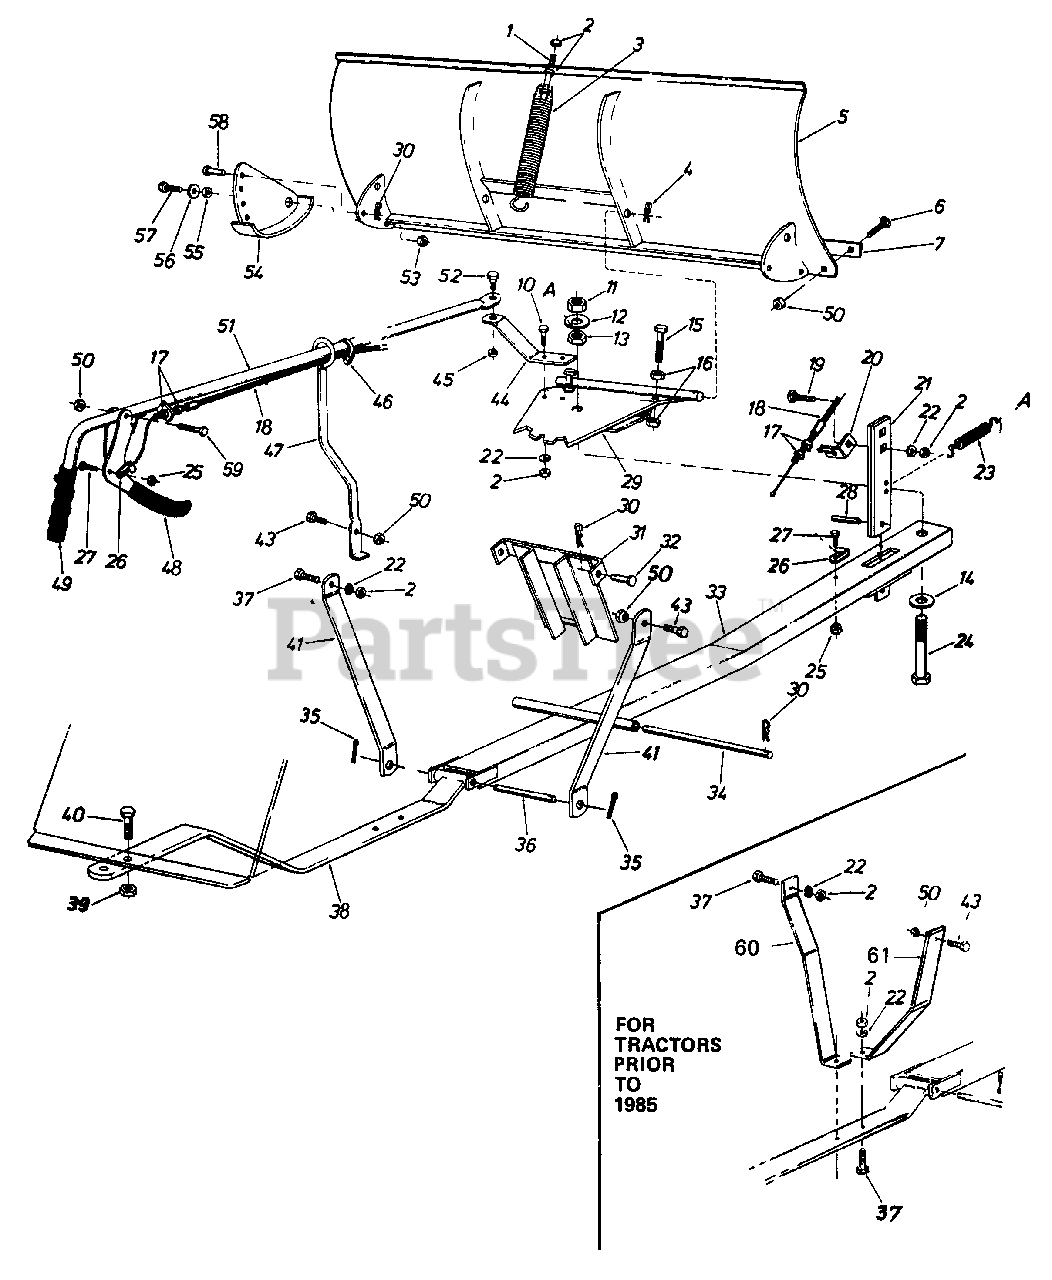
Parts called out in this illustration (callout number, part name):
1	Hex Scr. 3/8-16 x 4.50" Lg.*
2	Hex Nut 3/8-16 Thd.
3	Blade Adjustment Spring
4	Hair Pin Cotter 5/32" Dia.
5	48" BladeAss'y.
6	Carriage Bolt 5/16-18 x.75" Lg.*
7	Wear Plate 48"
10	Hex Scr. 3/8-16 x 1.00" Lg. *
11	Hex L.-Nut 3/4-10 Thd.
12	Fl.-Wash..810" I.D. x 2.00" O.D.
13	Hex Jam Nut 3/4-10 Thd. *
14	Fl.-Wash..810" I.D. x 2.00" O.D.
15	HexScr. 1/2-13x 2.00" Lg.*
16	Hex Nut 1/2-13 Thd. *
17	Hex Jam Nut 5/16- 0 24 Thd.*
18	Control Cable Ass'y.
19	Carriage Bolt 3/8-16 x 1.25" Lg.*
20	Cable Guide Bracket
21	Angle-Lock Bar
22	L.-Wash. 3/8" Scr.*
23	Angle Lock Spring
24	Hex Scr. 3/4-10 x 4.00" Lg.
25	Hex L.-Nut 1/4-20 Thd.
26	Clevis Lanyard Fitting
27	Hex Scr. 1/4-20 x .75" Lg.*
28	Spring Pin Spirol 1/4" Dia. x 1.00" Lg.
29	Pivot Plate Ass'y.
30	Hair Pin Cotter 3/32" Dia.
31	Guide Bracket Ass'y.
32	Clevis Pin 1/2" Dia. x 1.00" Lg.
33	Push Bar Ass'y.
35	Cotter Pin 5/32" Dia. x 1.00" Lg.*
37	Hex Scr. 3/8-16 x 1.25" Lg.*
38	Hanger Bracket Ass'y.
39	Hex L.-Nut 5/8-11 Thd.
40	Hex Scr. 5/8-11 x 1.50" Lg.*
41	Hanger Link
43	Hex 5/16-18 x 1.00" Lg. *
44	Blade Pivot Bracket
45	Hex L.-Nut 3/8-16 Thd.
46	Nylon Cable Tie
47	Tube Guide Ass'y.
48	Clutch Grip Ass'y.
49	Grip-3/4" Handle
50	Hex L-Nut 5/16-18 Thd.
51	Tube Handle Ass'y.
52	Shld. Scr.-Special 3/8-16 Thd.
53	Hex L.-Nut 3/8-16 0 Thd.
54	Skid Assembly
55	Spacer
56	Fl.-Wash..385" I.D. x 1.00" O.D.
57	Hex Scr. 3/8-16 x .75" Lg.*
58	ClevisPin5/16" Dia. x.75" Lg.
59	Hex Scr. 5/16-18 x 1.50" Lg.
60	Mounting Brkt.-L.H.
61	Mounting Brkt.-R.H.
